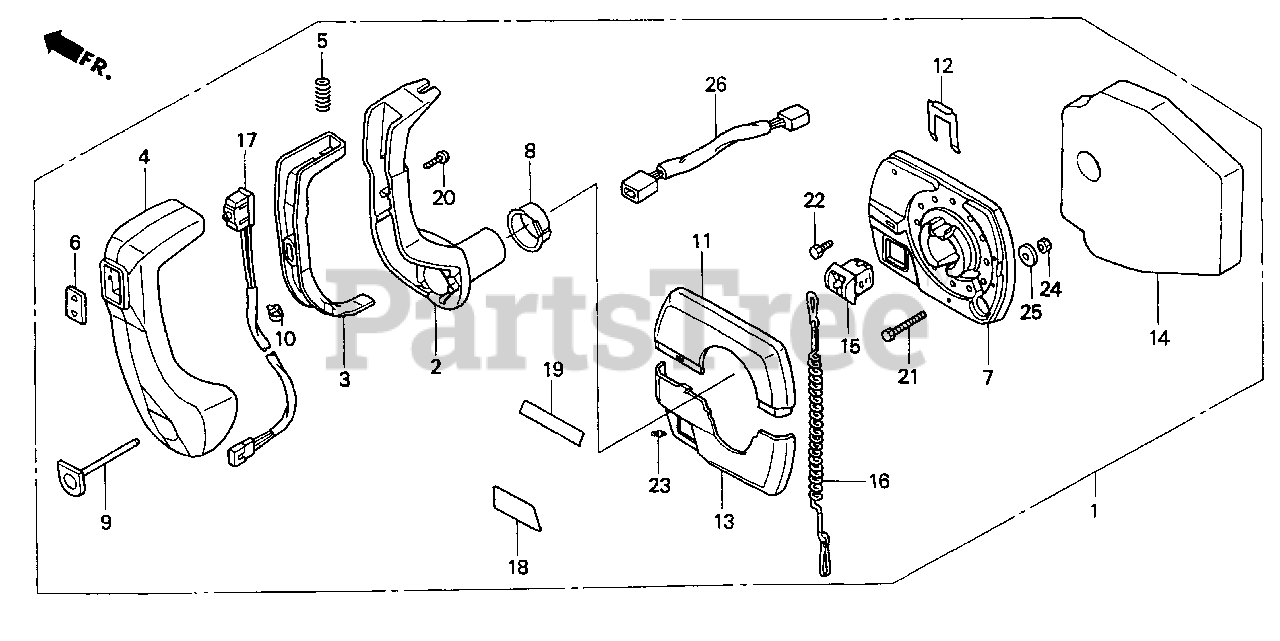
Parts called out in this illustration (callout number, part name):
1	BOX ASSY., REMOTE CONTROL (PANEL MOUNT)
2	HANDLE, REMOTE CONTROL
3	LEVER, HANDLE LOCK
4	GRIP, REMOTE CONTROL HANDLE
5	SPRING, REMOTE CONTROL HANDLE
6	COVER, GRIP
7	HOUSING ASSY., REMOTE CONTROL BOX (A)
9	BUTTON, THROTTLE
10	BAND B, CABLE
11	HOUSING ASSY., REMOTE CONTROL BOX (B)
13	HOUSING, REMOTE CONTROL BOX (C)
14	HOUSING ASSY. (INNER) (PANEL MOUNT)
15	SWITCH ASSY., EMERGENCY STOP
16	WIRE, EMERGENCY
17	SWITCH ASSY., POWER TRIM-TILT (A)
18	MARK, REMOTE CONTROL (A)(PANEL)
19	MARK, R. REMOTE CONTROL (B)
19	MARK, L. REMOTE CONTROL (C)
23	SCREW SET (1/4-20X16")
24	NUT (1/4X20)
26	HARNESS ASSY., POWER TRIM-TILT Use from Frame SN 4000384.
